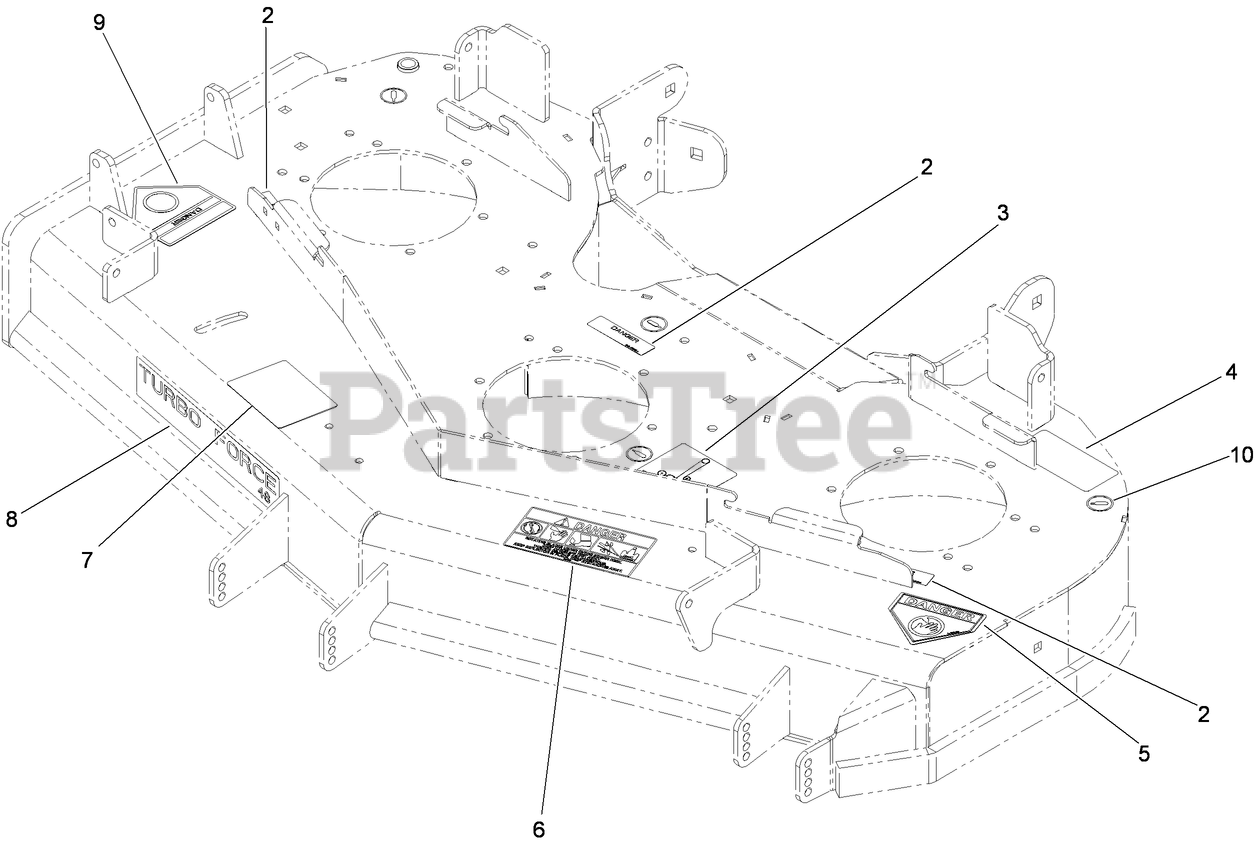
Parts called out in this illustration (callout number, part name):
2	DECAL-COVER, MISSING
3	DECAL-ROUTING, DECK BELT
4	DECAL-TORQUE
5	DECAL-DANGER
6	DECAL-DANGER, THROWN OBJECT
7	DECAL-SCALP, ANTI
9	DECAL-DANGER
10	DECAL-GREASE
